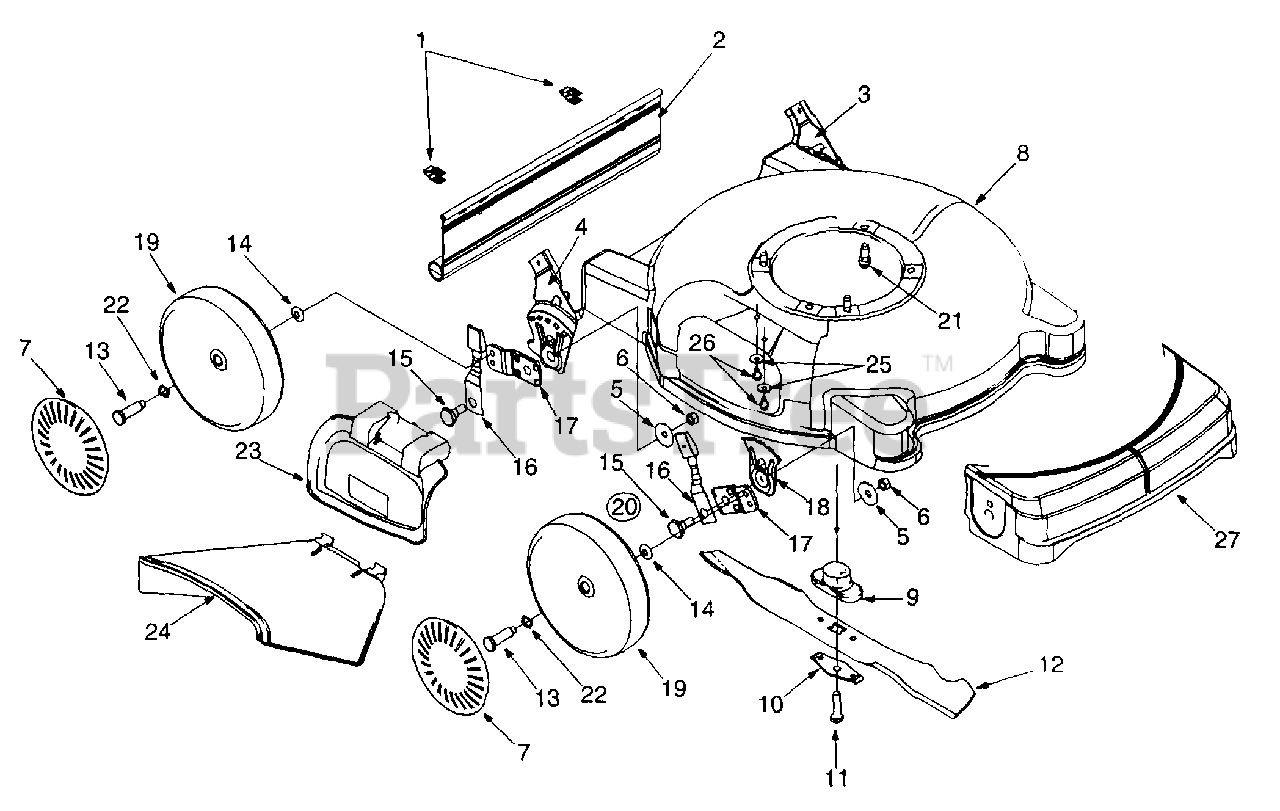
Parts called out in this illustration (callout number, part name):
1	Hinge Clip
2	Rear Flap
5	Bell Washer .39" ID x 1.38"
6	Hex Nut 3/8-16 Thd.
7	Hub Cap: Yellow
10	Blade Bell Support
11	Hex Bolt 7/16-20 x 1.5"
12	20" Mulch Blade
13	Axle Bolt
14	Bell Washer.400" ID x.88"
15	Shoulder Bolt
16	Spring Lever Ass'y w/Knob
18	Height Adj. Plate
19	Wheel Assembly
20	Height Adj. Ass'y. Comp. R.F.
21	Hex Lock Wash. Hd. Screw 3/8-16 x 1.0" Lg.
22	Wave Washer
23	Mulching Plug
24	Chute Deflector
25	Bell Washer
26	Hex Wash. Hd. TT Screw 1/4-20 x .5" Lg.
27	Cover: Front End
